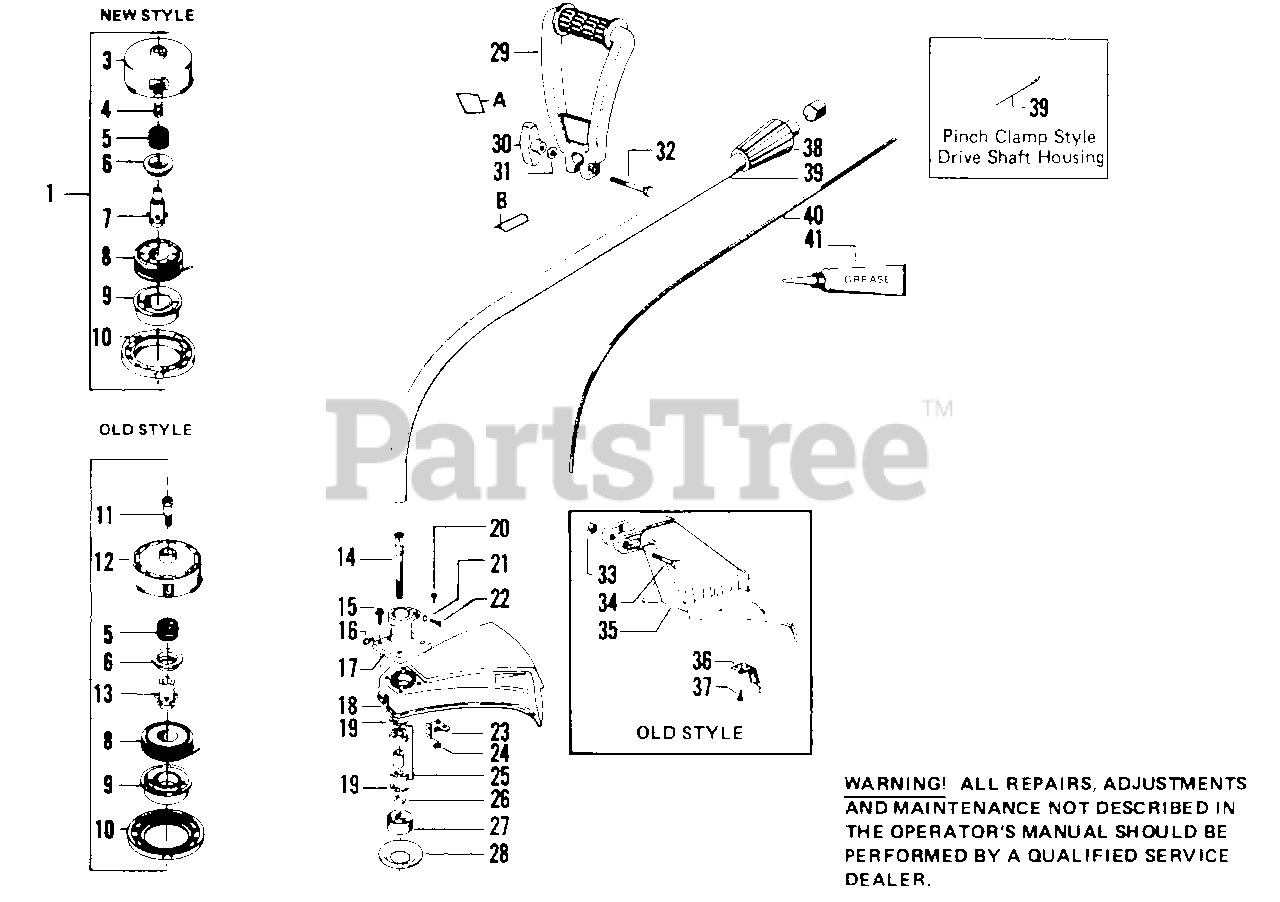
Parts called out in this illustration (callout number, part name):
1	Cutting Head Ass'y - New Style (Inc.3 -10)
3	Hub w/Line Saver - New Style
4	Line Saver
5	Spring
6	Adptor - Spring
7	Drive Gear - New Style
8	Spool w/Line
9	Release Button
11	Bolt - Drive Adaptor - Old Style
12	Hub w/Line Saver - Old Style
13	Drive Gear - Old Style
14	Shaft - Arbor
15	Screw - #1/4 - 10 x 1-1/8" - Shield to Bearing Housing
16	Screw - #5/16 - Self Tapping
17	Bearing Housing Ass'y (Inc.'s 14, 19, 21, 22, 25, 26 & 27)
18	Model 2600 - 14"
18	Model 2600,2610 - 17"
18	Model 2610 - 18"
19	Retainer - Bearing
20	Screw - #10 - 24 x 5/8" - Line Limiter
21	Washer - #1/4 Int. Tooth Lock
22	Screw - #1/4 - 20 x 1" Pinch Clamp
24	Nut - #10 - 24" - Locking
25	Bearing & Spacer Kit
26	Washer - 3/8" - Dust Cup
27	Dust Cup
29	Assist Handle
29	Model 2600
29	Model 2610
30	Knob - #1/4 - 20" - Model 2610
31	Washer - 1/4" Flat
32	Hex Bolt - #1/4 - 20 x 1-1/2"
33	Wing Nut - Shield 14"
34	Hex Bolt - #1/4 - 20 x 1-1/2" - Shield 14"
35	Model 2600 - 14"
36	Line Limiter - Shield 14"
37	Screw - Line Limiter (14") to Shield
38	Collar Nut
39	Drive Shaft Housing Collar Nut Style
39	Model 2600 (34")
39	Model 2610 (41")
40	Flexible Drive Shaft
40	Model 2600 (34")
40	Model 2610 (41")
41	Flex Shaft Lube
A	Warning Label - Assist Handle
B	Decal - Blade Warning
